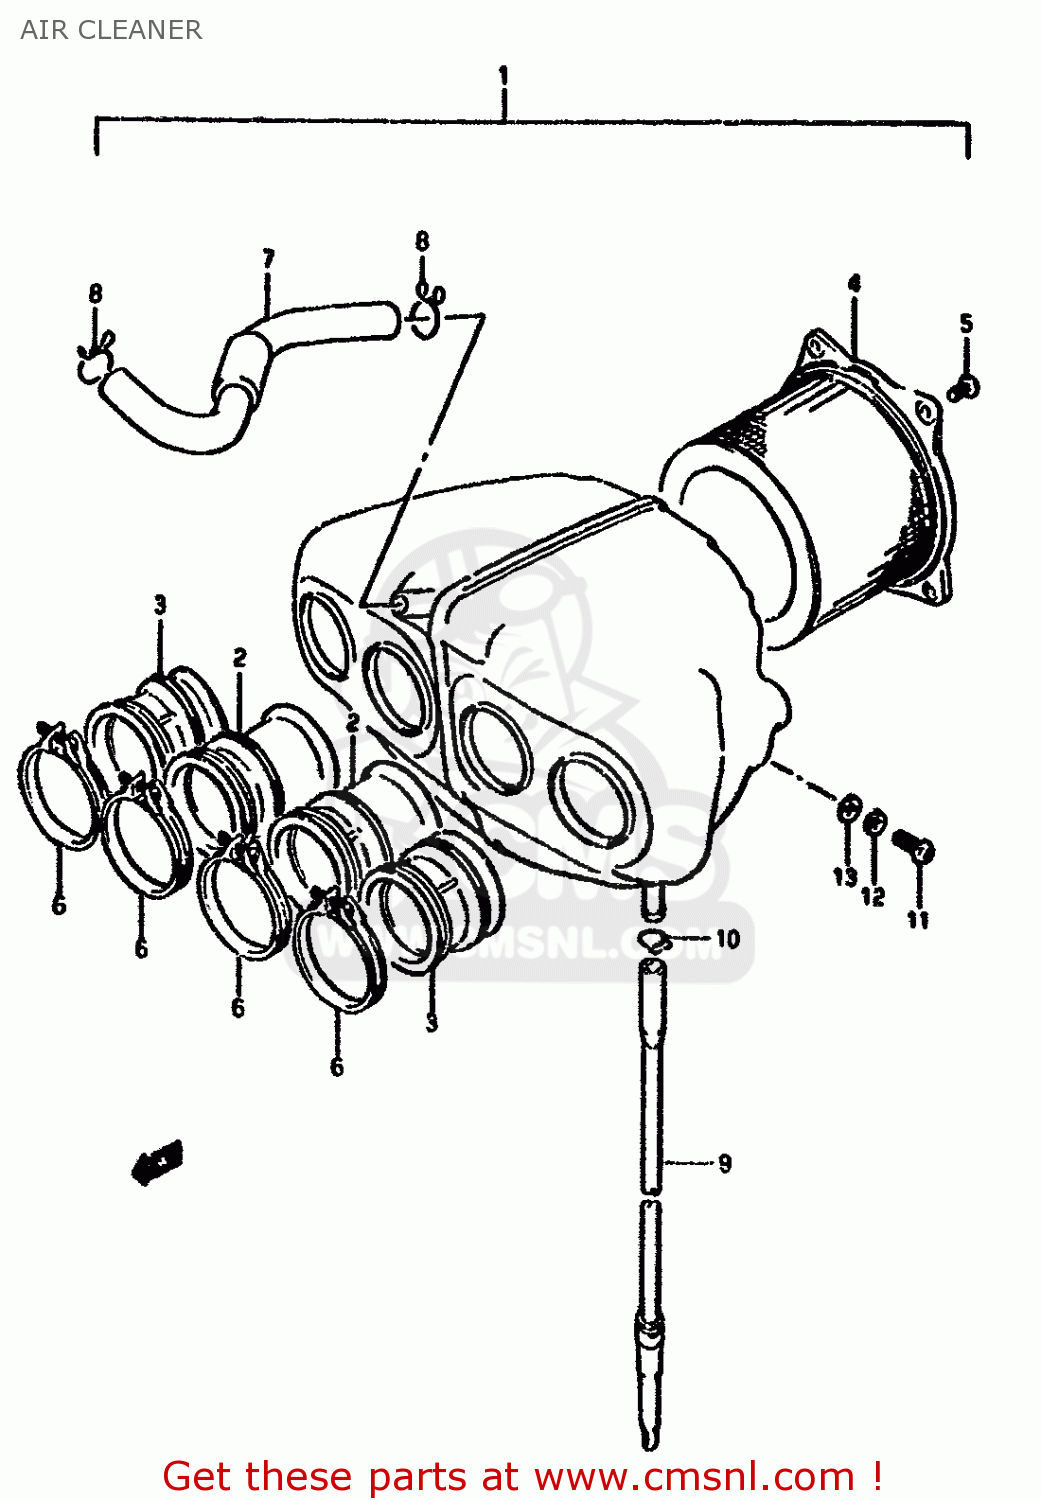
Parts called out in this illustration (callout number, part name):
1	CLEANER ASSEMBLY,AIR
2	TUBE,OUTLET NO.1
3	TUBE,OUTLET NO.2
4	FILTER,AIR CLEANER
5	SCREW, FRONT & REAR
6	CLAMP
7	TUBE,BREATHER
8	CLIP
9	DRAIN TUBE
10	CLIP
11	SCREW
12	WASHER,LOCK
13	WASHER
